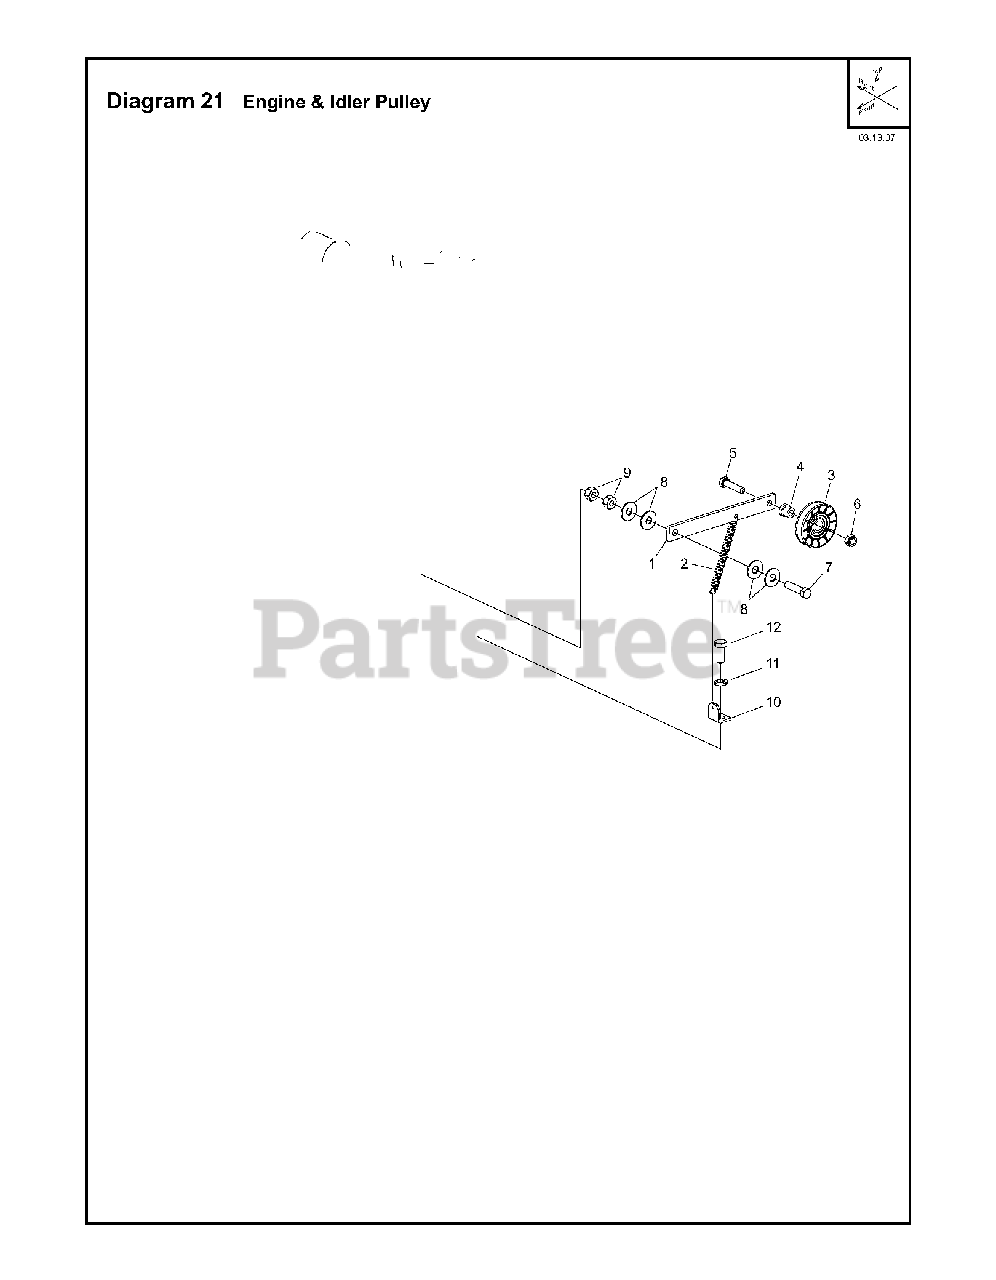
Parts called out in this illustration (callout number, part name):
1	IDLER LEVER - PC BLACK
5	HHCS. M10 x 1.5 x 45 DIN933 ZP
6	LOCKNUT. FIBER M10 DIN 985
7	HHCS. .4375-14 x 1.75 GR 5 Z/P
10	DECAL
11	LOCKWASHER. SPLIT .5 Z/P
12	HHCS. M12 x 1.75 x 30 DIN933ZP
